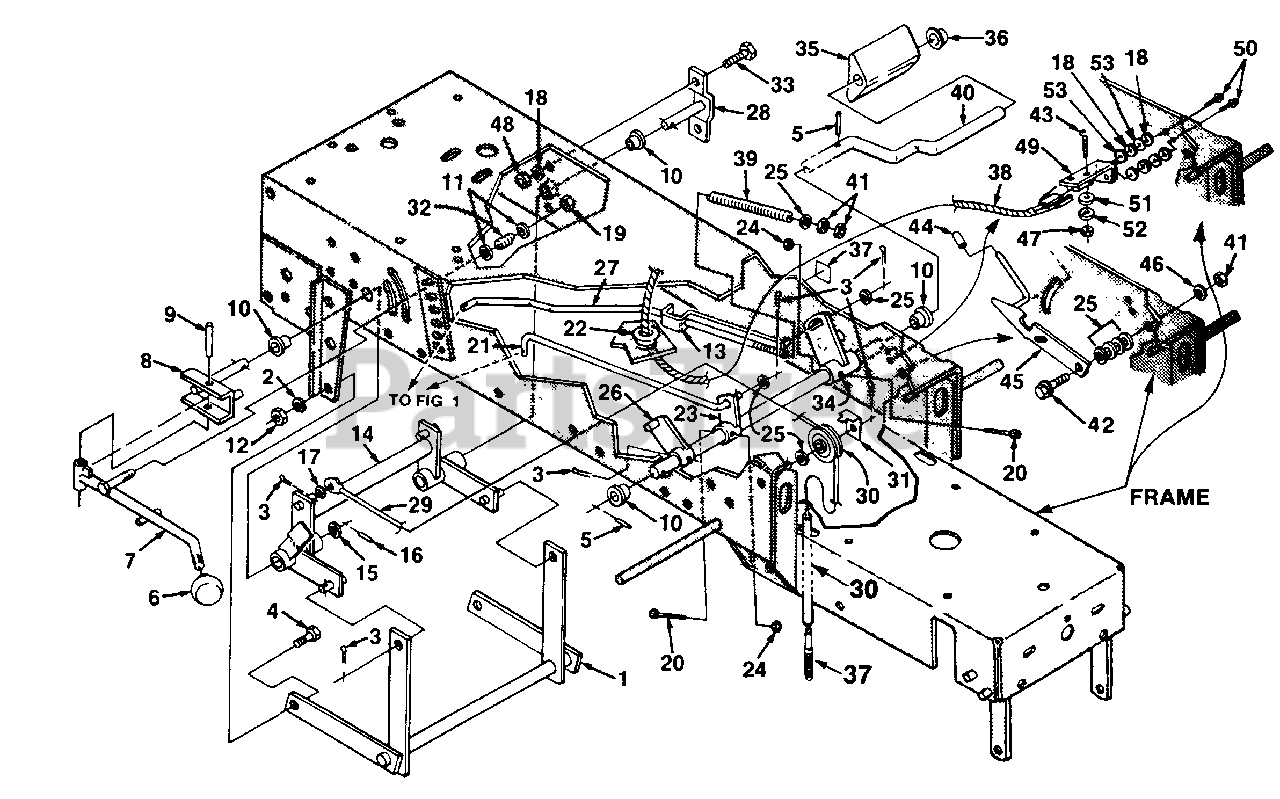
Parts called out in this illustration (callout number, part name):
1	LIFT BAR ASSY.
2	WASHER- Lock Hvy. (3/8")
3	PIN- Cotter (3/32 x 3/4")
4	BOLT- Shoulder
5	PIN- Roll (1/8 x 1")
6	KNOB- Shift Lever
7	HANDLE ASSY.
8	HANDLE- Lift
9	PIN- Groove
11	WASHER- Flat (3/8")
12	NUT- Hex (3/8 x 16)
13	BRACKET- Brake Spring
14	REAR LIFT & BUSHING
15	WASHER- Flat (5/8")
16	PIN- Roll
17	WASHER- Flat (3/8")
18	WASHER- Lock (1/4")
19	NUT- Lock (5/16-18)
20	SCREW- Socket
21	ROD- Idler Act.
22	BUSING- Snap
23	LEVER- Clutch
24	NUT- C'lock (#10-24)
25	WASHER- Flat (5/16")
26	ARM- Deactivating
27	ROD- Brake
28	FLANGE & ROD ASSY
29	CABLE- Lift
30	PULLEY- Lift Cable
31	RETAINER- Cable
32	SPRING- Compression
33	SCREW- Hex hd. cap (1/4-20 x 5/8")
34	BRAKE LEVER
35	PEDAL- Clutch
36	NUT- Push
37	DECAL- Park Brake
38	SWITCH- Safety
39	SPRING- Comp Brake
40	ARM- Brake/Clutch
41	NUT- (5/16-18)
42	BOLT- Shoulder (5/16-18)
43	SCREW- Slotted Truss Hd. (#4-40 x 1")
45	LATCH & LEVER
46	WASHER- Lock Hvy. (5/16")
47	NUT- Hex (#4-40)
48	NUT- Hex (1/4-20)
50	SCREW- (1/4-14 x .44)
51	WASHER- Flat (#4)
52	WASHER- Lock (#4)
53	WASHER- Flat (1/4")
